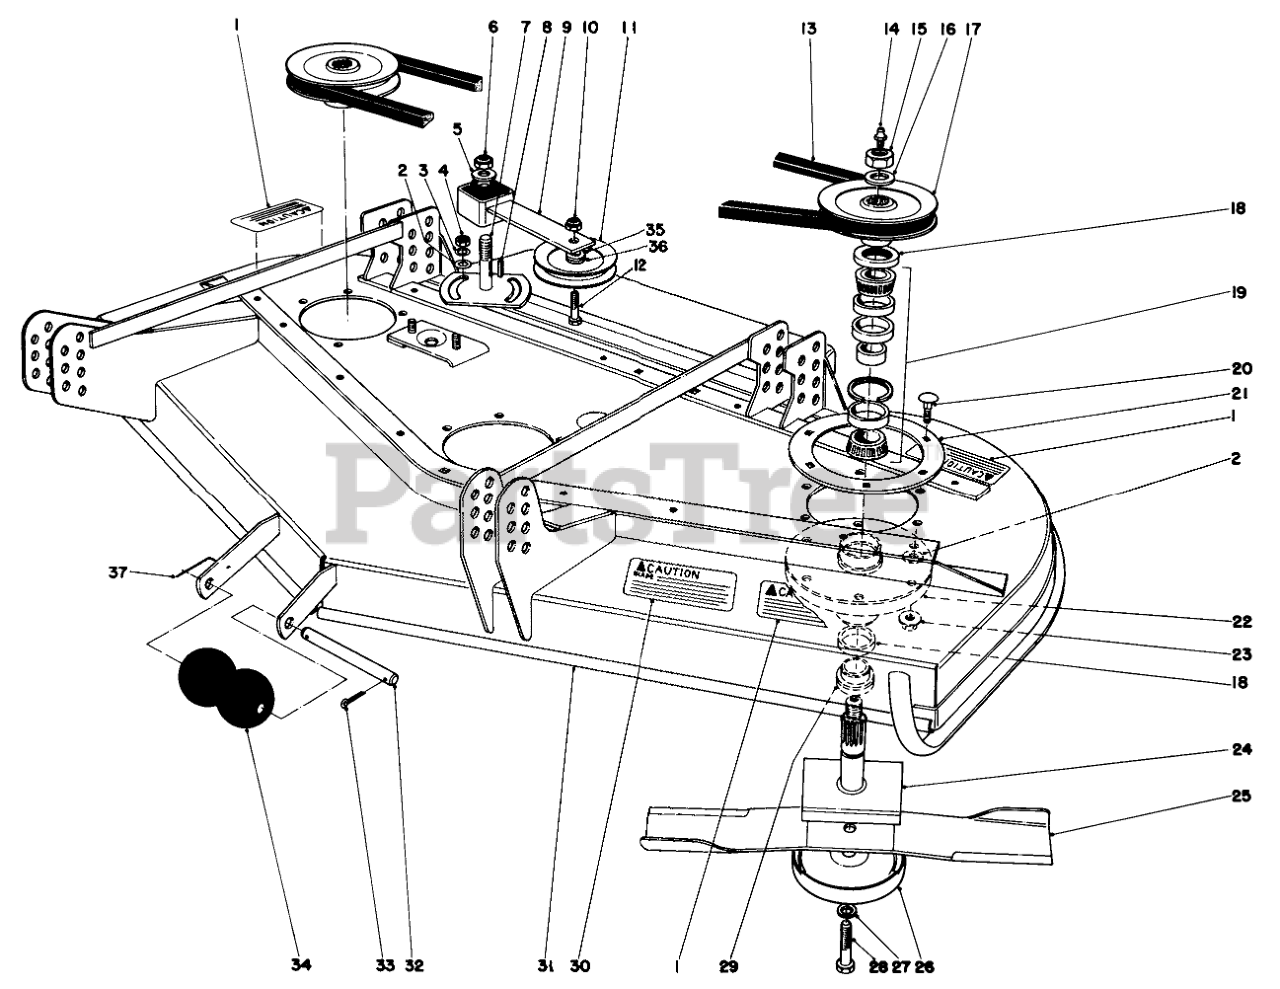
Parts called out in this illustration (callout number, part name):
1	DECAL-CAUTION, BLADE
2	WASHER-FLAT
3	WASHER-LOCK
4	NUT-JAM
5	WASHER-FLAT
6	NUT-LOCK, NI
7	PLATE-IDLER
8	KEY-SQUARE
9	IDLER ARM ASM
10	NUT-HEX
11	PULLEY-IDLER
12	SCREW-HH
13	V-BELT
14	FITTING-GREASE
15	NUT-HEX
16	WASHER
17	PULLEY AND HUB ASM
18	SEAL-OIL
19	BEARING ASM
20	SCREW-CARR
21	SUPPORT-DECK, RING
22	HOUSING-SPINDLE
23	NUT-HF
24	SHAFT
25	Blade
26	Cup-Scalp
27	WASHER-LOCK
28	SCREW-BLADE
29	SPACER
30	Decal-Caution
31	CUTTER DECK WA RO
32	SHAFT-ROLLER
33	PIN-COTTER
34	ROLLER
35	WASHER-FLAT
36	BUSHING-PULLEY
37	PIN-SPECIAL
